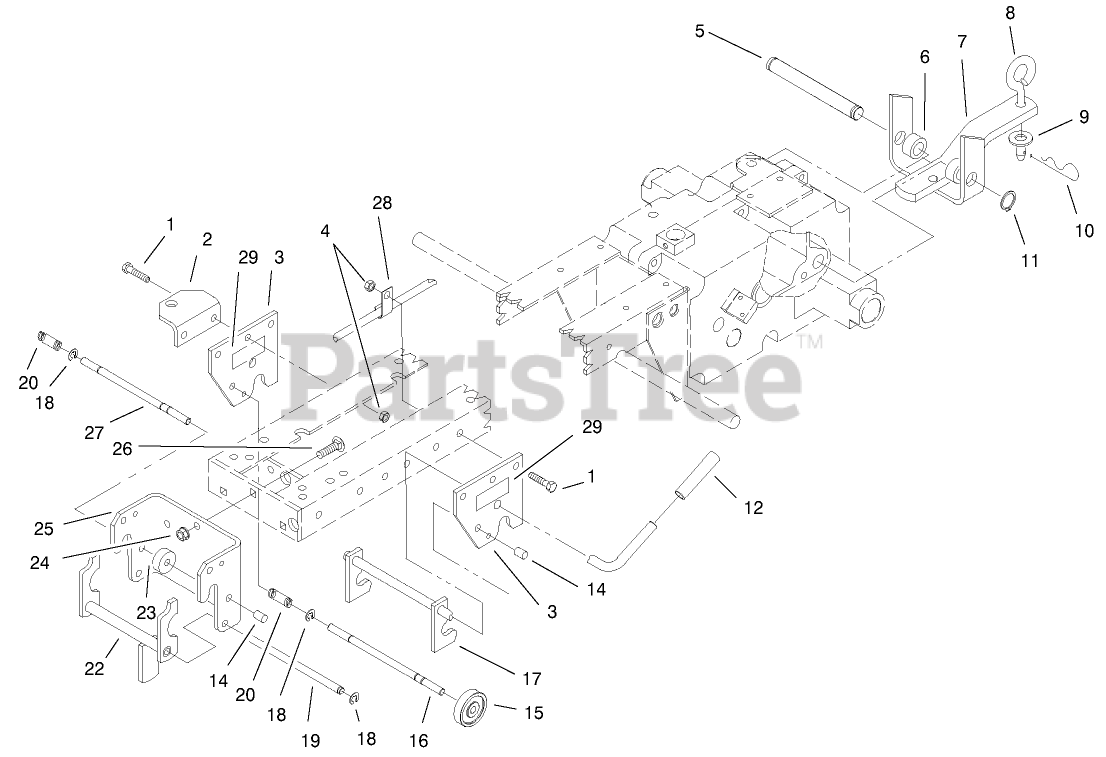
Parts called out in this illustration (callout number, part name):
1	SCREW-HH
2	SUPPORT
3	PLATE-HITCH
4	NUT-HEX
5	PIN-STATIONARY HITCH
6	SPACER
7	HITCH ASM
8	PIN-TOOL
9	WASHER-FLAT
10	PIN-HAIR
11	E-RING
12	GRIP
14	CAP-ROD, PLUNGER
16	ROD-LOCK
17	MID HITCH ASM
18	RING-RETAINING
19	ROD-LATCH PIVOT
20	SPRING
22	LATCH
24	NUT-LOCK, NI
25	HITCH-FRONT
26	BOLT-CARR
27	ROD-LOCK
28	CLIP
29	DECAL-ATTACH A-MATIC
